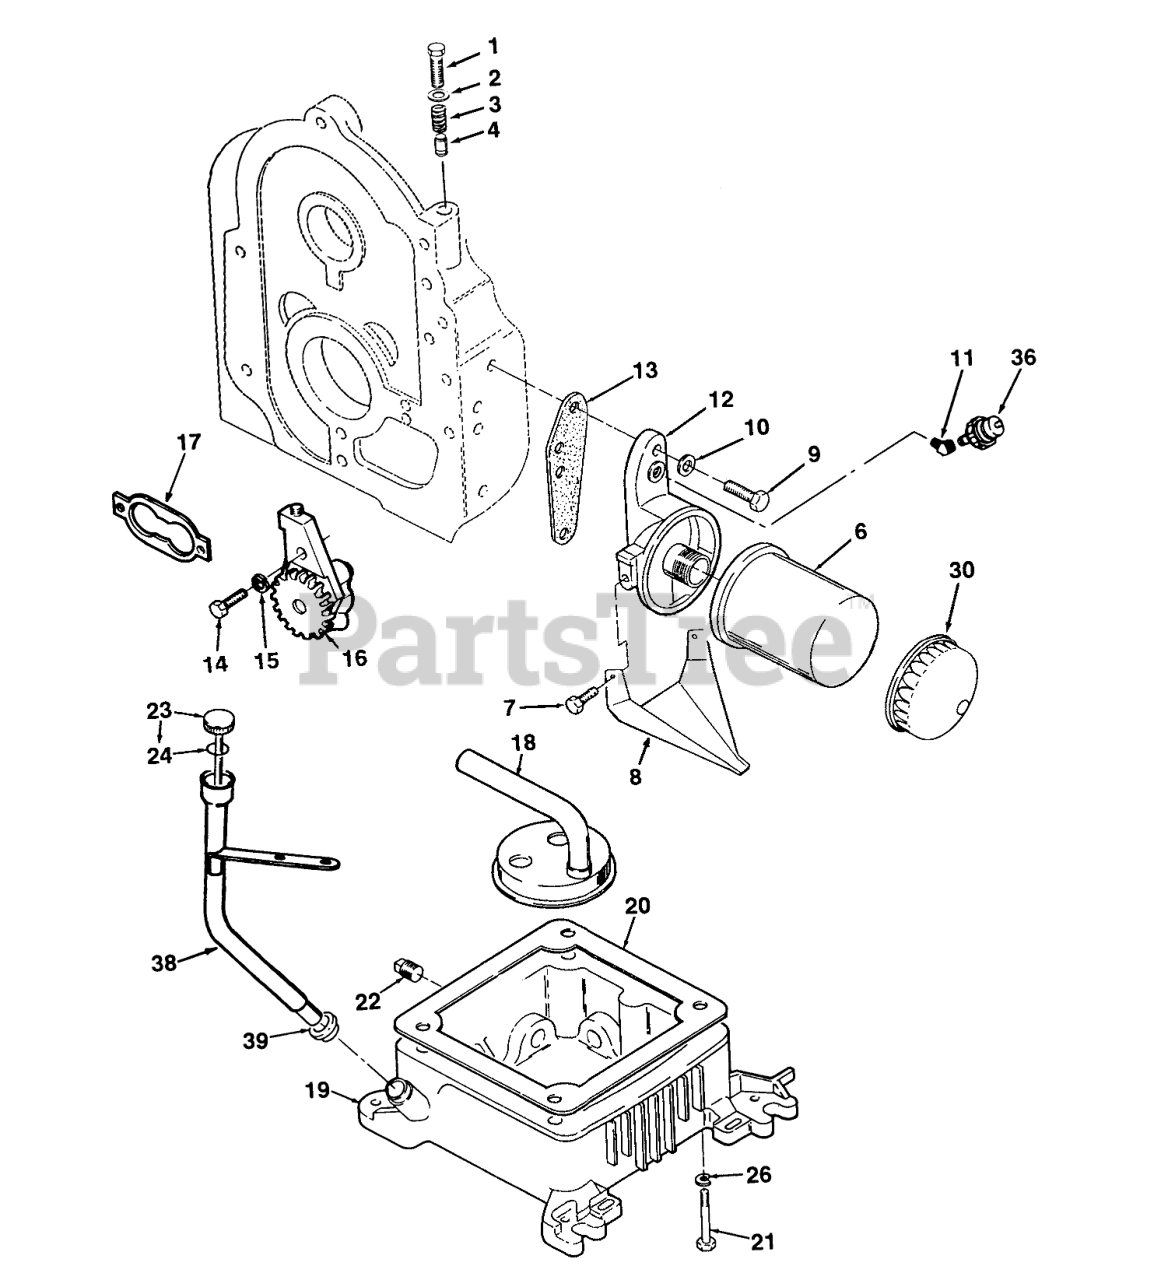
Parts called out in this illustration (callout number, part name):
1	Bolt
2	Washer
3	Spring, Bypass
4	PLUNGER
6	FILTER-OIL
7	SCREW-HH
8	DRAIN-OIL FILTER
9	HHCS 5/16-18 X 1
10	WASHER
11	ELBOW-45 DEG
12	ADAPTER-OIL FILTER
13	Gasket
14	SCREW - CAP HEX HEAD
15	WASHER-FLAT
17	GASKET KIT
18	CUP-OIL PUMP INTAKE
19	Base-Oil (Incl. Plugs)
20	GASKET
21	Screw
23	Oil Fill Cap & Indicator (Incl. O-Ring)
24	SEAL 0-RING
26	WASHER-FLAT
30	WRENCH-OIL FILTER
36	OIL-PRESSURE SWITCH
38	TUBE-OIL FILTER
39	SEAL-OIL FILL TUBE
